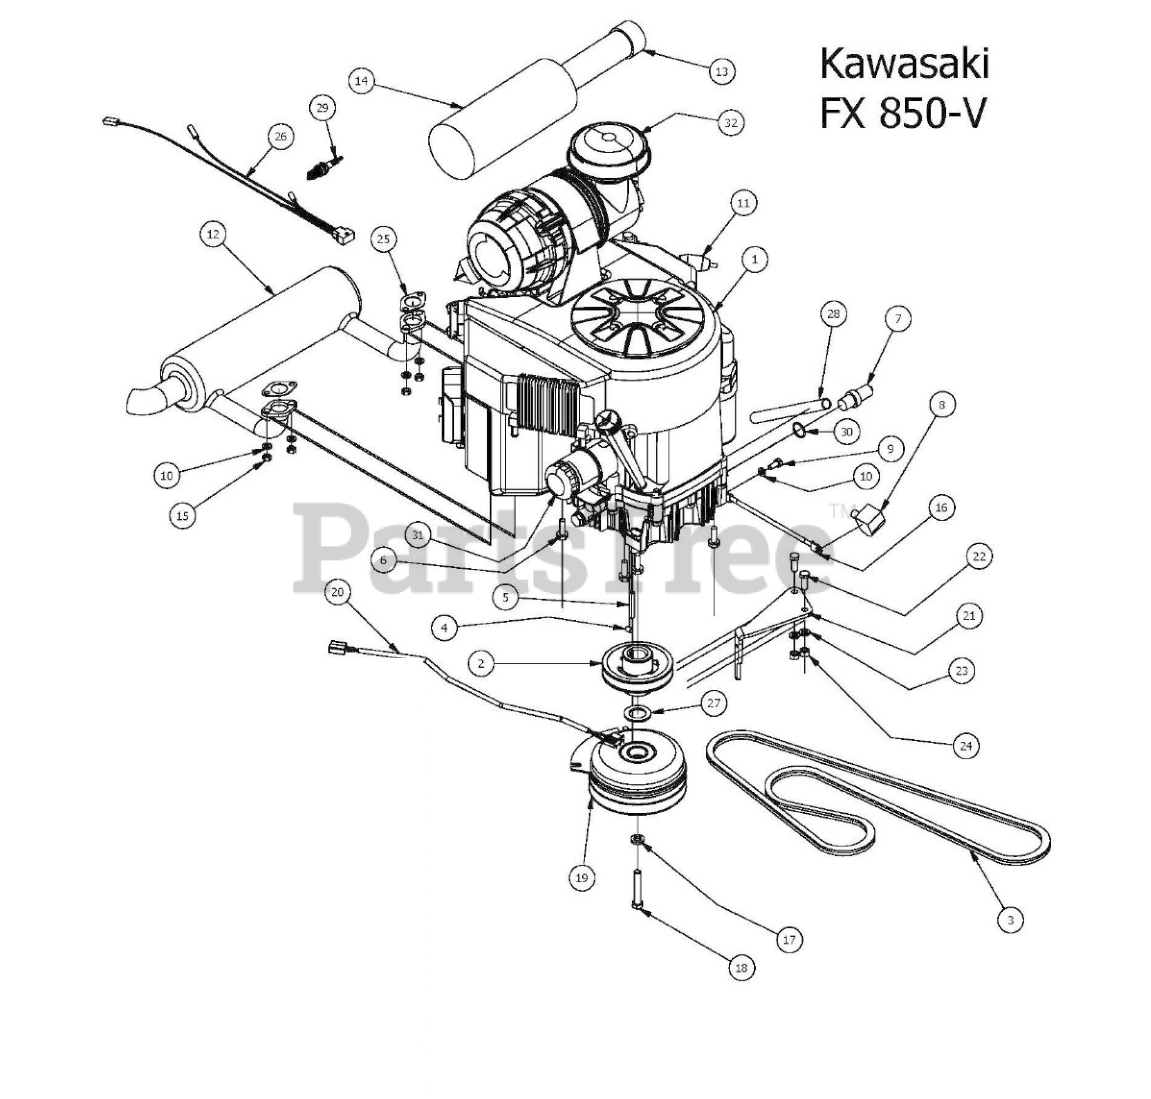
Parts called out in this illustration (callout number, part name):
1	Kawasaki Engine FX-850-V-CS09R
2	4 3/4 Motor Pulley
4	3/8" Set Screw
5	1/4 x 2 Square key Stock
6	3/8 x 1 1/8 bolt
8	Black Boot For Ground Cable
9	M8x1.20x20MM Hex head bolt
10	5/16" Lock Washer
11	Universal Inline Fuel Filter
12	Kawasaki Exhaust
13	Canister Air Filter- Inner
14	Canister Air Filter-Outer
15	M8-1.25 Zinc Nut
16	Ground Cable
17	7/16" Lock Washer
18	7/16" x 21/2" Hex Bolt
19	Clutch Assembly
20	Clutch Pigtail
21	PTO Engager Holder
22	3/8" x 1" Hex Bolt
23	3/8" Lock Washer
24	3/8" Hex Nut
25	Exhaust Gasket
26	Hamess Adaptor
27	1 1/8" Flat Spacer
28	1/2 Clear Braded Hose Priced/Foot
29	Spark Plug - Kawasaki
31	Kawsaki Oil Filter
32	Kawasaki Rain Cap
